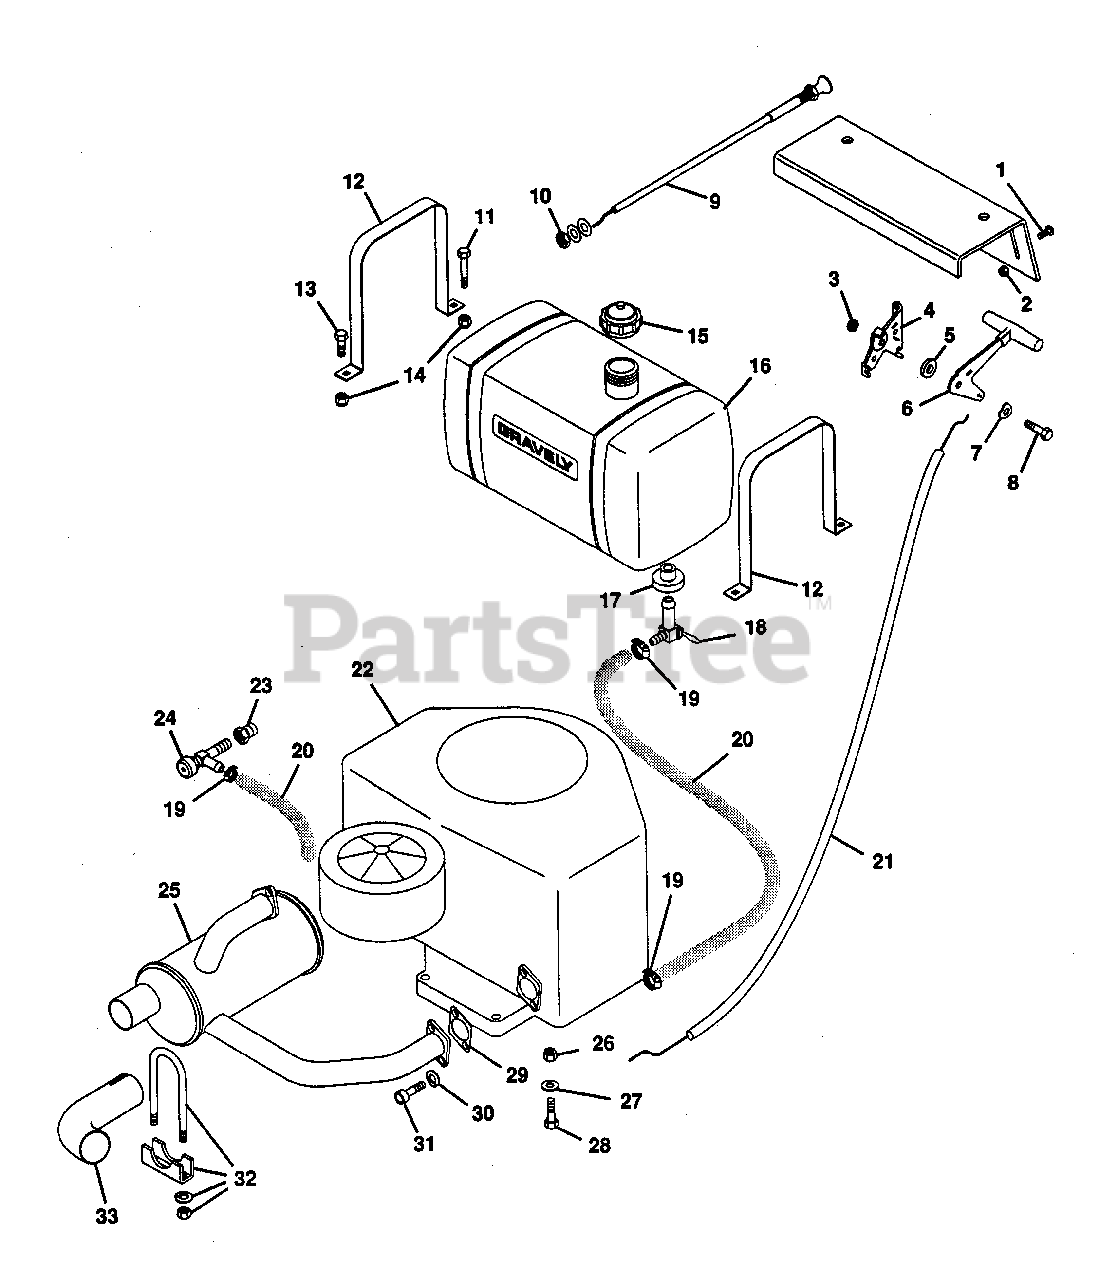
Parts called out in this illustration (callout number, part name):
1	Screw, Mach. 10-32x.50 PHD
2	Nut, Lock 10-32
3	Nut, Lock 1/4-28
4	Bracket, Mounting L.H.
5	Washer, Friction
6	Assembly, Knob and Lever
7	Washer, Spring
8	Bolt, Hex 1/4-28x.75
9	Control, Choke
10	Nut, Jam 3/8-24 Hex
11	Bolt, Hex 1/4-20x1.75
12	Strap, Fuel Tank
13	Bolt, Hex 1/4-20x.625
14	Nut, Lock 1/4-20
15	Cap, Fuel Tank
16	Tank, Fuel
17	Bush., Flg..375x1.06x.625 Rb.
18	Valve, Ball Shut-off
19	Clamp, Hose
20	ft. Line, Fuel
21	Assembly, Throttle Conduit
22	Engine, 20 HP Kohler
23	Adaptor, Oil Drain
24	Cock, Oil Drain
25	Muffler
26	Nut, Lock 5/16-18
27	Washer, Flat .344x.688x.065
28	Bolt, Hex 5/16-18x1.50
29	Gasket, Exhaust
30	Washer, Lock 5/16 Reg.
31	Screw, Cap 5/16-18x.75 SHD
32	Clamp, U 1.75
33	Deflector
